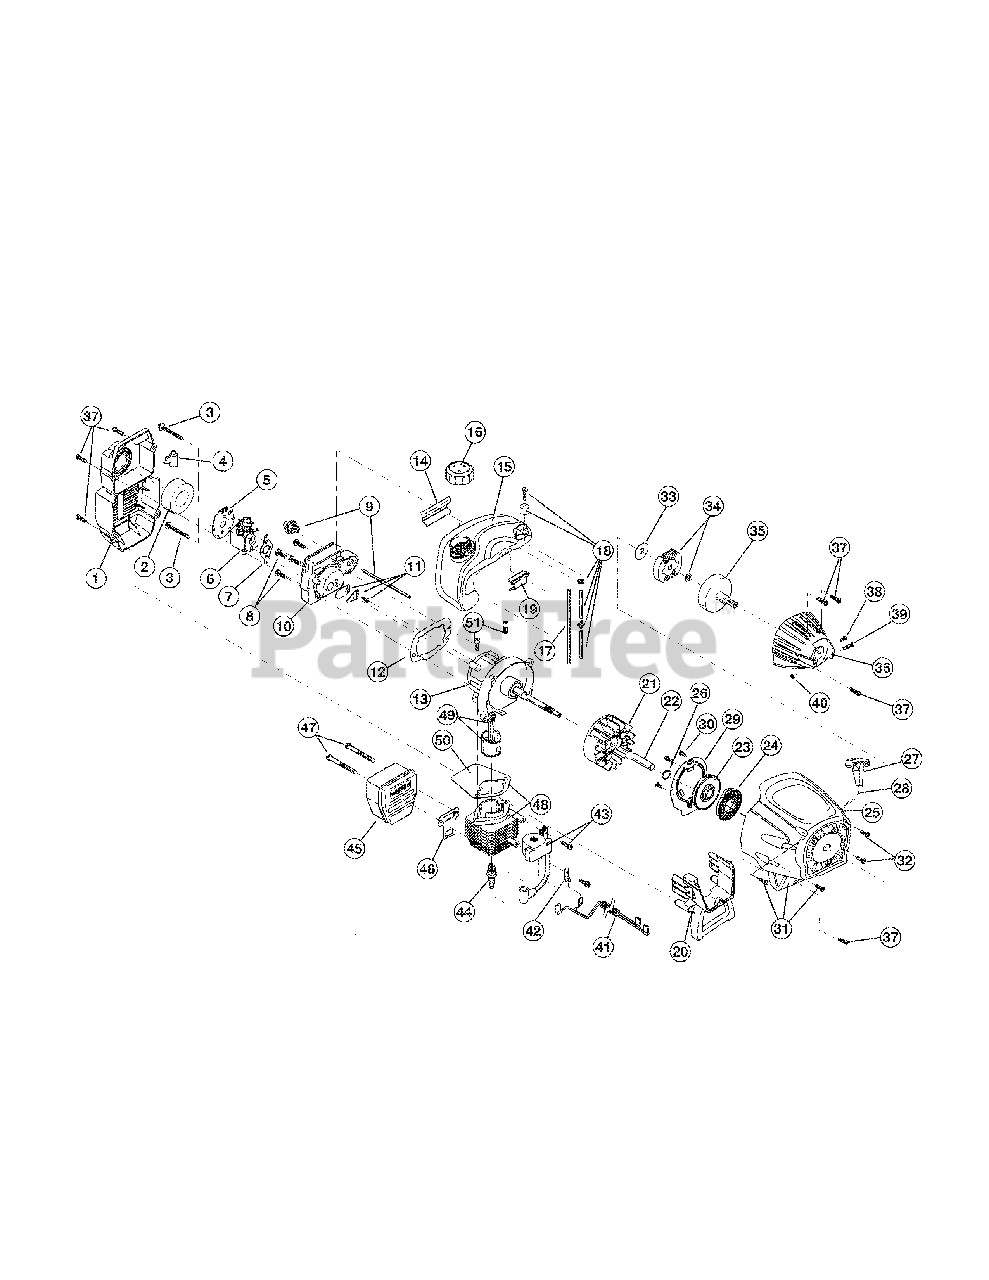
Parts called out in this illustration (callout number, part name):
1	Air Cleaner Cover Assembly (includes 2 & 37)
2	Air Cleaner Filter
3	Carburetor Mounting Screw Assembly
4	Choke Lever
5	Choke Plate
6	Carburetor Assembly (includes 7 & 18)
7	Carburetor Gasket
8	Carb Mount Screw
9	Primer and Hose Assembly
10	Carb Mount Assembly (includes 8, 11 & 12)
11	Reed Assembly
12	Carburetor Mount Gasket
13	Crank Case Service Assembly (includes 10)
14	Rear Mounting Pad
15	Fuel Tank Assembly (includes 16-18)
16	Fuel Cap Assembly
17	Fuel Return Line
18	Fuel Line Assembly
19	Front Mounting Pad
20	Shroud Extension & Stand (includes 37)
21	Flywheel Assembly
23	Recoil Pulley Assembly
24	Recoil Spring
25	Rope Guide
26	Pulley Retainer
27	Pull Handle
29	Pressure Plate Assembly (includes 30)
30	Plate Screw
31	Starter Housing Assembly (includes 23-30, 32 & 37)
32	Housing Screw
33	Clutch Washer
34	Clutch Rotor Assembly
35	Clutch Drum Assembly
36	Clutch Cover Assembly (includes 37-40)
37	Cover Screw
38	Anti-Rotation Screw
39	Clamping Screw
40	Clamping Nut
41	Wire Leads and Sleeve
42	Ground Tab
43	Module Assembly
44	Spark Plug
45	Muffler Assembly (includes 46 & 47)
46	Exhaust Gasket
47	Muffler Mounting Bolt Assembly
48	Cylinder Assembly (includes 51 & 52)
49	Piston and Rod Assembly
50	Cylinder Gasket
51	Cylinder Bolt
